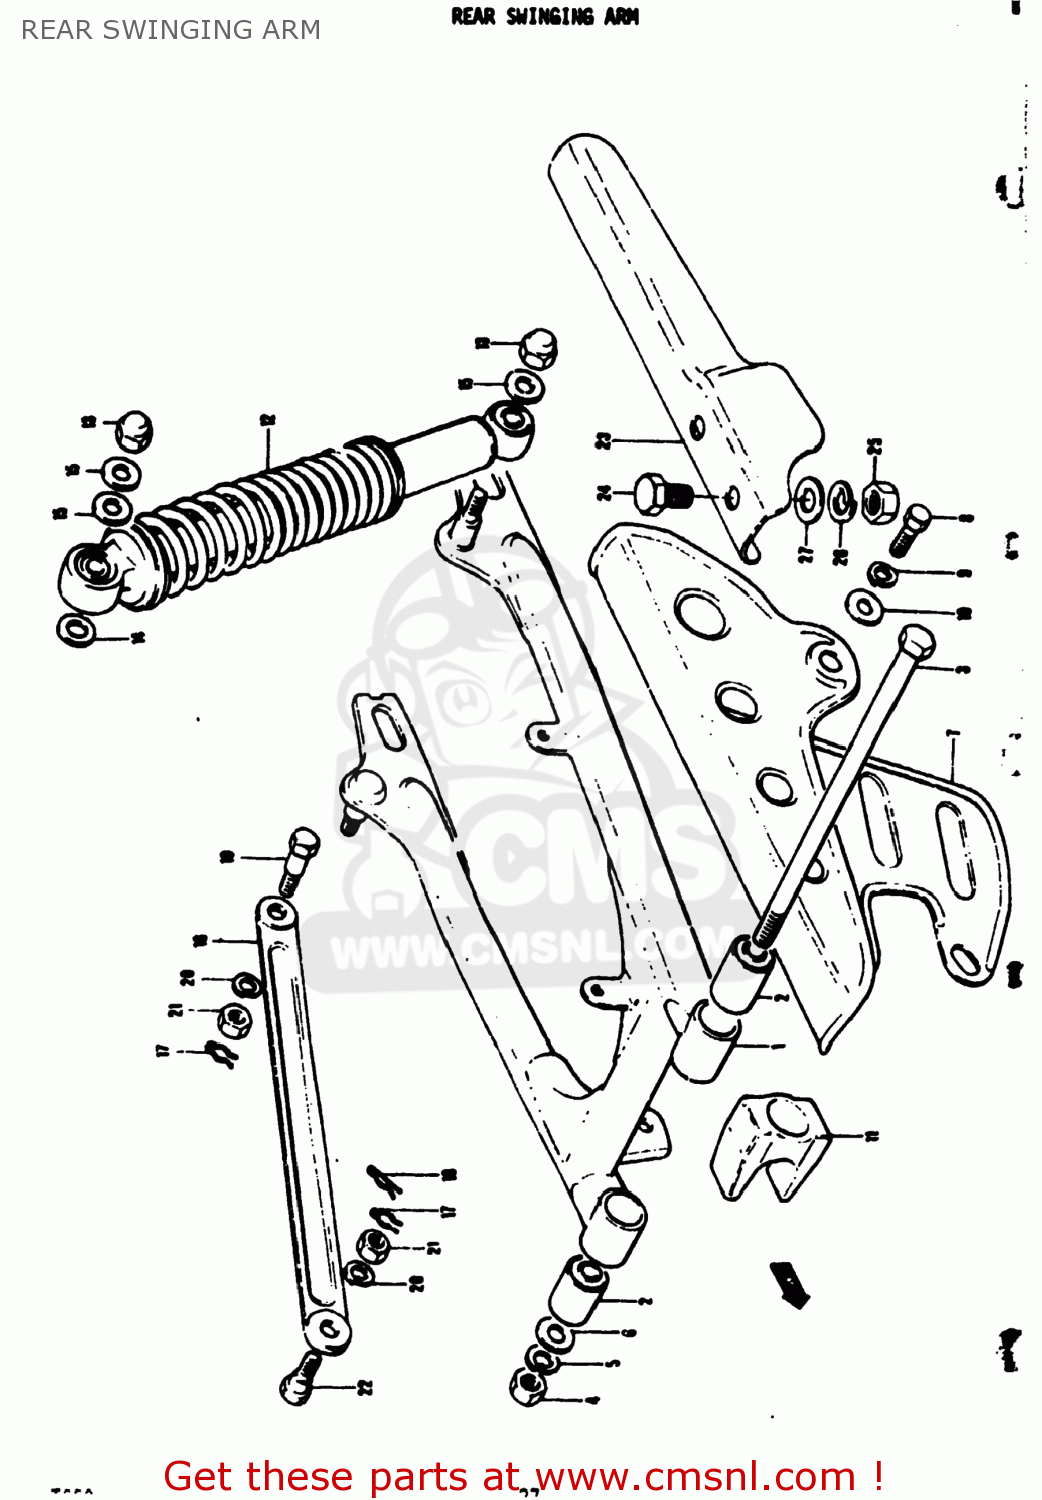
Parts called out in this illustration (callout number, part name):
1	SWING ARM ASSEMBLY,REAR
2	BUSHING(10X23X35)
3	SHAFT,RR SHOCK ABSORBER UPR
4	NUT
5	LOCK WASHER
6	WASHER
7	CASE,CHAIN
8	BOLT(6X8)
9	LOCK WASHER
10	WASHER
11	BUFFER,CHAIN TOUCH DEFLECTOR
12	ABSORBER ASSEMBLY,REAR SHOCK
13	NUT
14	WASHER
15	WASHER
16	TORQUE LINK,REAR
17	RETAINER,SNAP
18	CLIP
19	BOLT(8X26.5)
20	LOCK WASHER
21	NUT
22	BOLT(8X22.5)
24	BOLT
25	NUT
26	LOCK WASHER
27	WASHER
